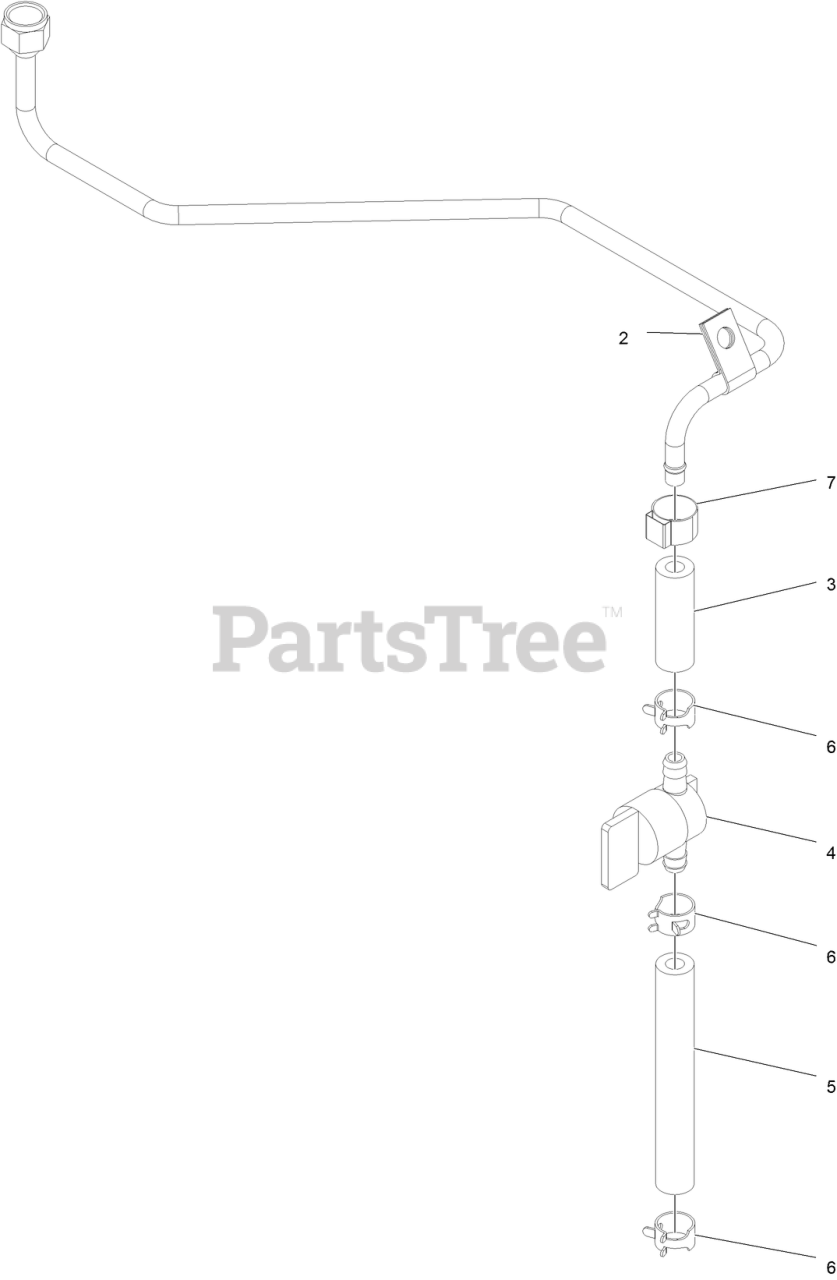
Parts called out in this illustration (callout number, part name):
2	CLIP-CLOSED, INSULATED
3	Hose-Fuel
4	VALVE-FUEL
5	HOSE-FUEL
6	CLAMP-HOSE
7	Clamp-Hose, Fuel
